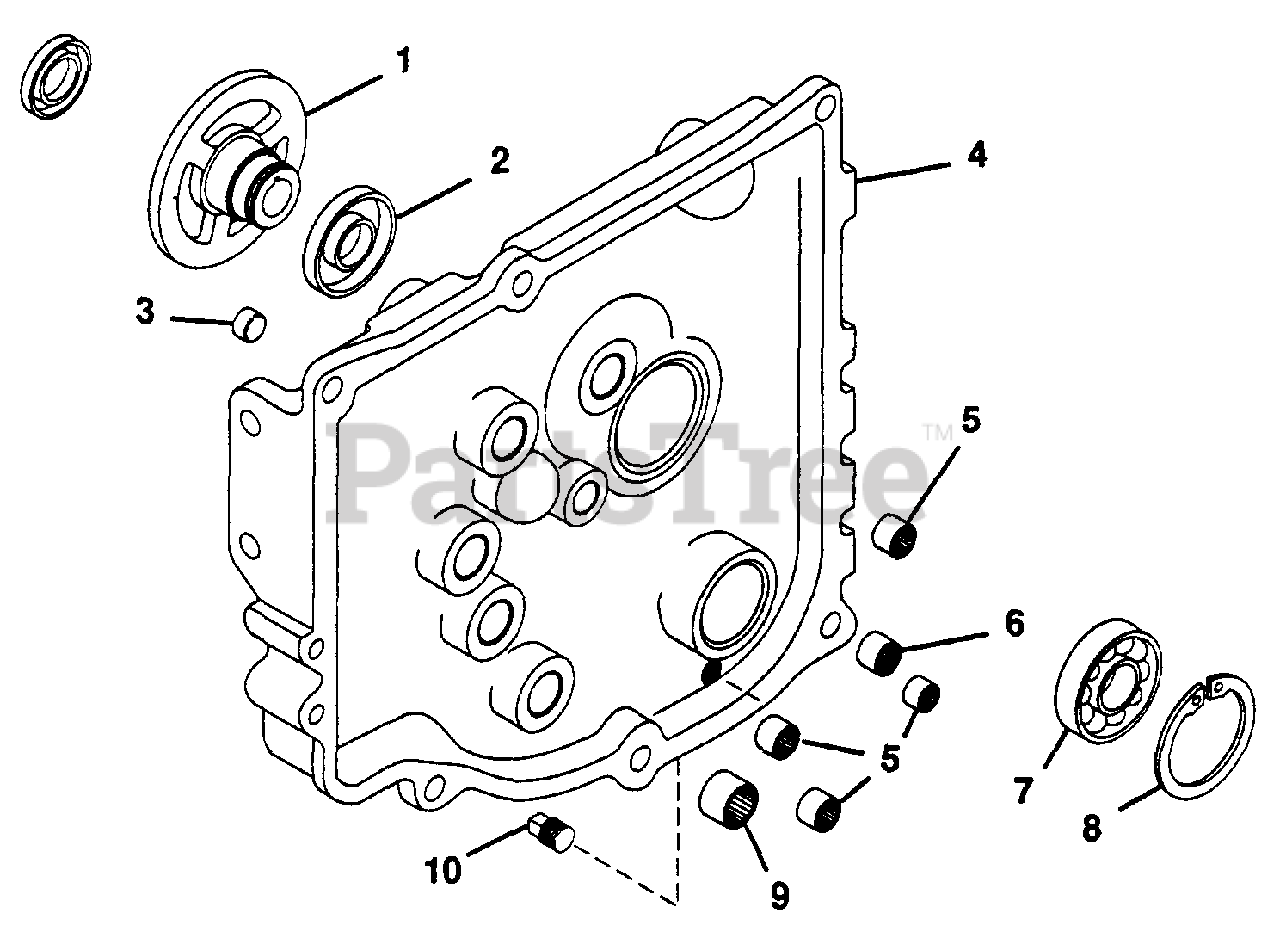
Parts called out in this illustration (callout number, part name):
1	Hub, Clutch
2	Seal, Oil
3	Plug, Cup 3/4
4	Assembly, Transmission Cover
5	Bearing, Needle .75x1x.75
6	Bearing, Needle .625x.812x.75
7	Bearing, Ball
8	Ring, Retaining .109 Thick
9	Bearing, Needle 1.000x1.250x.75
10	Plug, Pipe 3/8
